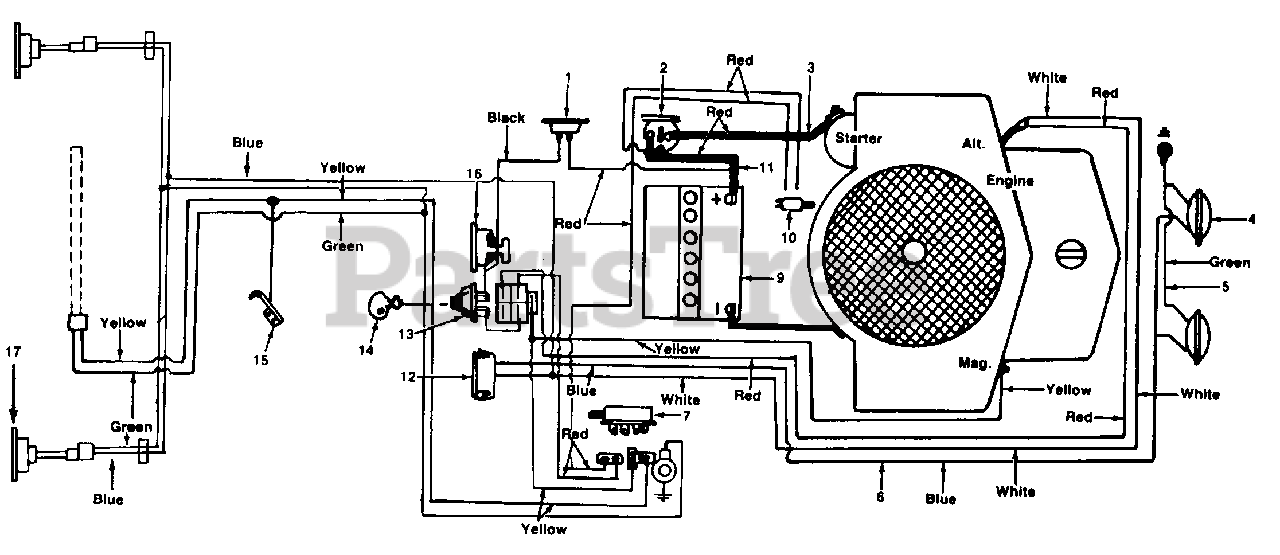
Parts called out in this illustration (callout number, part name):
1	Circuit Breaker
2	Solenoid
3	Wire
4	Headlight
5	Ground Wire
6	Wire Harness
7	Safety Switch
9	12V Battery
10	Safety Switch
12	Light Switch
13	Ignition Switch
14	Ignition Key
15	Spring Switch
16	Ammeter
17	Taillights
